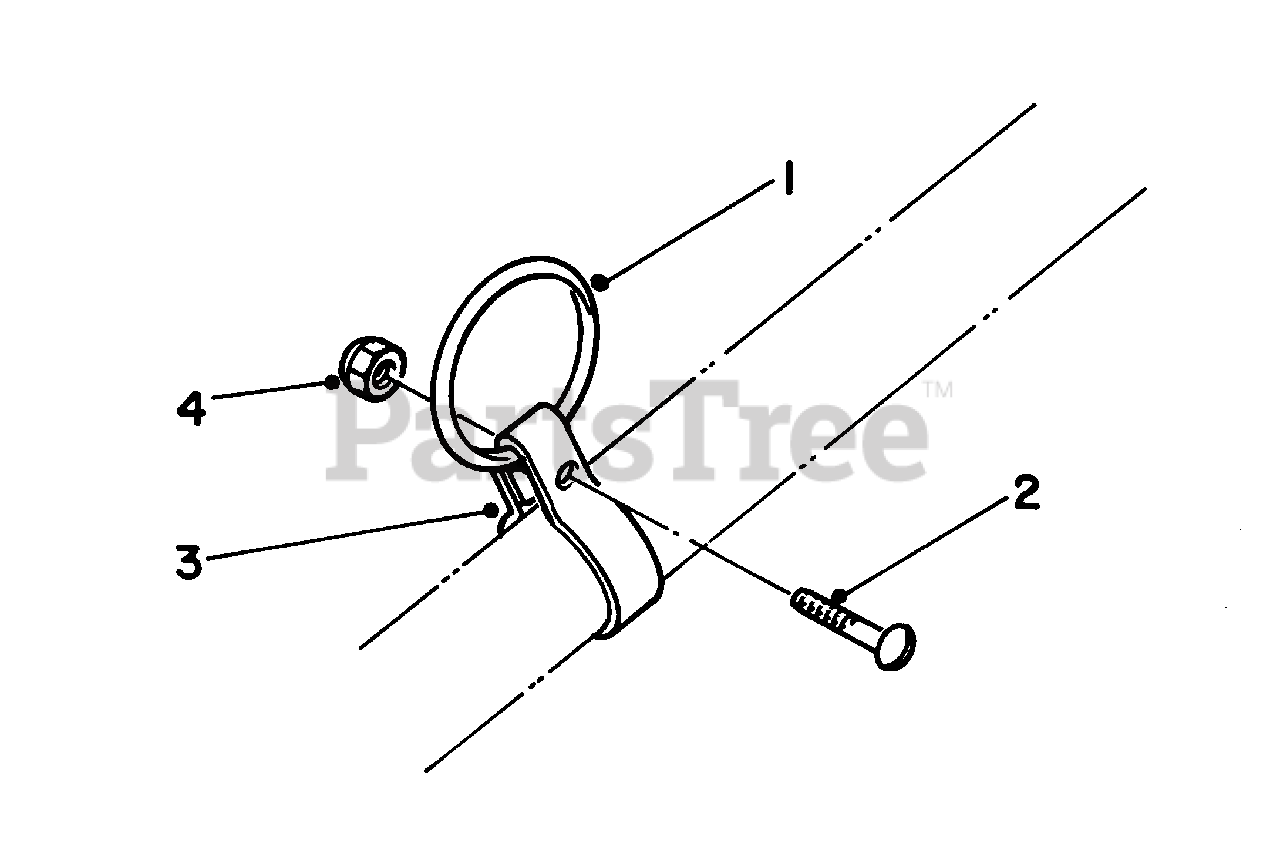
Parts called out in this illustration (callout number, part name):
1	Ring
2	Screw Rd. Hd. Machine
3	Clamp
